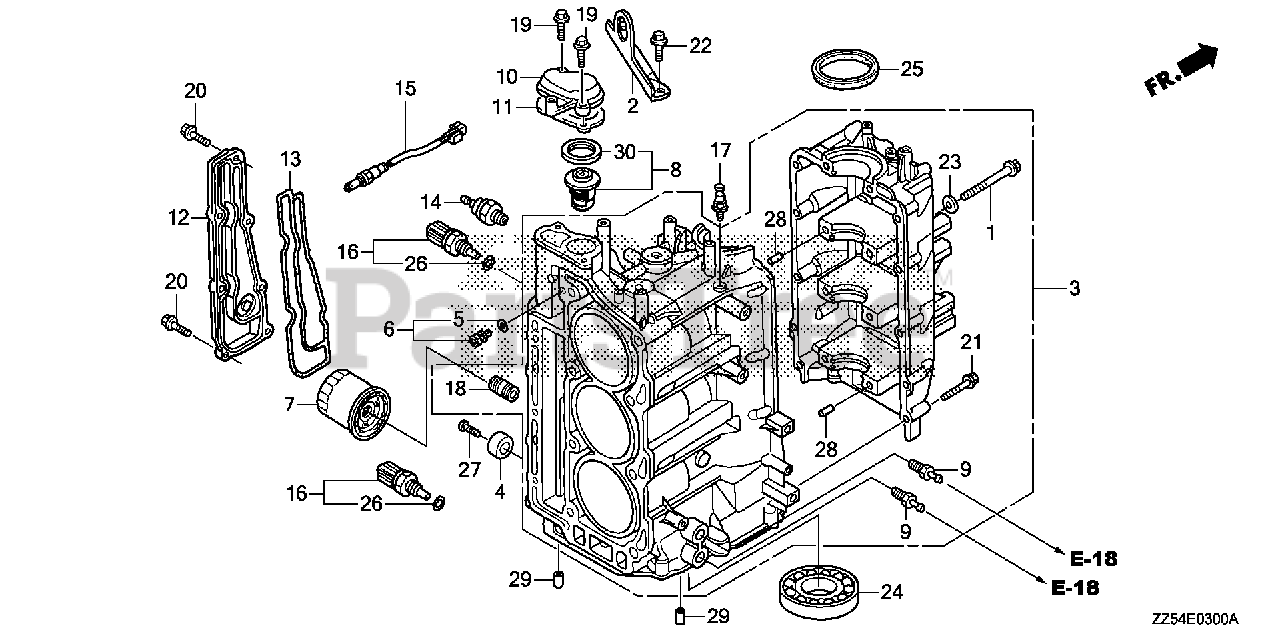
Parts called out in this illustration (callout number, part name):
1	BOLT, FLANGE (8X94)
2	HANGER, ENGINE
3	BLOCK ASSY., CYLINDER *NH8* (DARK GRAY)
4	METAL, ANODE
5	O-RING (4.8X1.9)
6	ORIFICE ASSY., OIL PASSAGE
7	FILTER, OIL (TOYO ROKI)
7	FILTER, OIL (DENSO)
8	THERMOSTAT ASSY.
9	JOINT, WATER TUBE
10	COVER, THERMOSTAT
11	GASKET, THERMOSTAT COVER
12	COVER, WATER JACKET
13	GASKET, WATER JACKET COVER
14	SWITCH ASSY., OIL PRESSURE
15	SENSOR, OXYGEN
16	SENSOR ASSY., WATER TEMPERATURE
17	BOLT, TIMING BELT ADJUSTING SPRING
18	HOLDER, OIL FILTER
19	BOLT, FLANGE (6X20)
20	BOLT, FLANGE (6X22)
21	BOLT, FLANGE (6X40)
22	BOLT, FLANGE (8X18)
23	WASHER, PLAIN (8MM)
24	BEARING, RADIAL BALL (6005)
25	OIL SEAL (56X70X8)
26	O-RING (9.5X1.5) (HONDA KIKAKI)
27	SCREW, PAN (6X18)
28	PIN, DOWEL (10X12)
29	PIN, DOWEL (6X10)
30	RUBBER, RING
